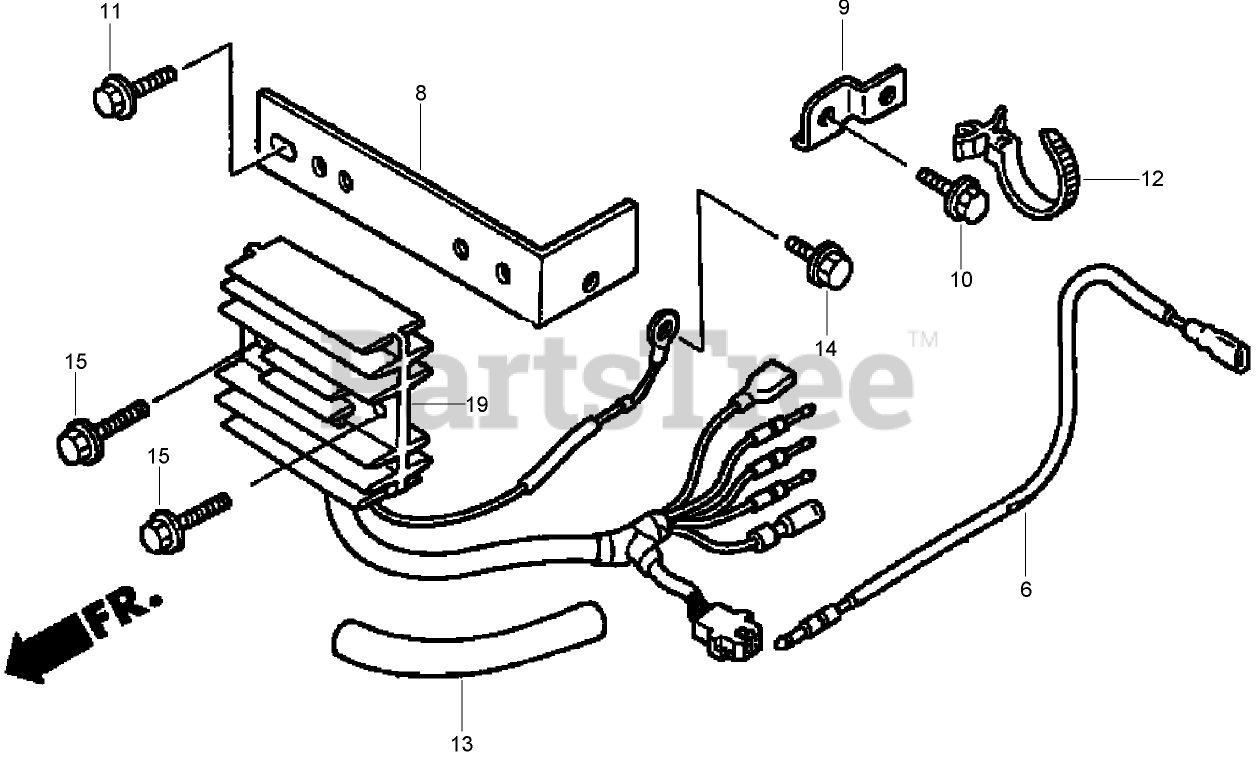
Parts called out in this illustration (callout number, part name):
6	SUB-WIRE HARNESS ASM
8	BRACKET-REGULATOR
9	BASE-CLIP
10	BOLT-FLANGE (6X12) (C T200)
11	BOLT-FLANGE (6X14) (C T200)
12	STRAP-CABLE (105MM) (N H1 BLACK)
13	TUBE-WIRE
14	BOLT-FLANGE (6X8)
15	BOLT-FLANGE (6X20)
19	REGULATOR RECTIFIER ASM
